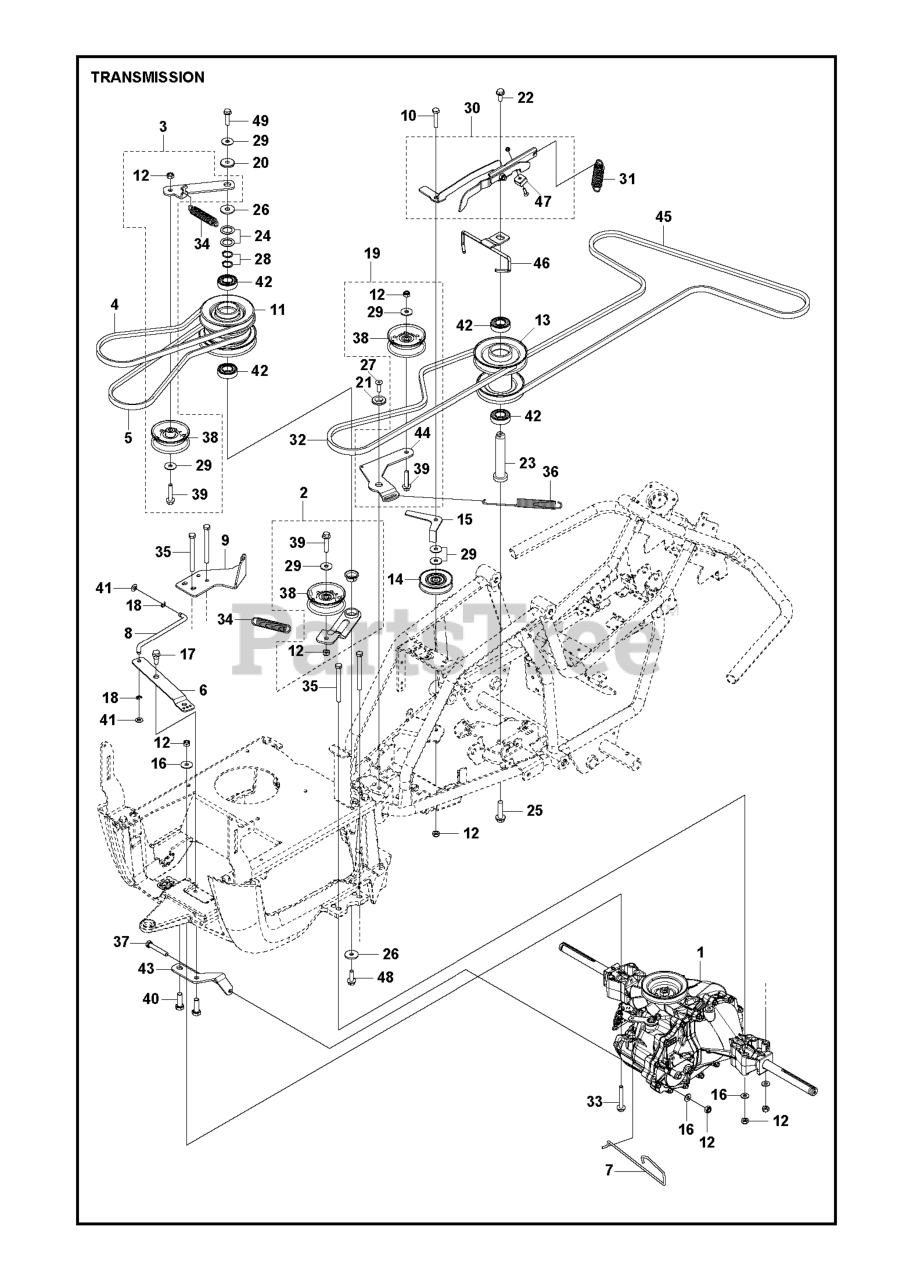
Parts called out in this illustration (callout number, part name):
2	BELT TENSIONER ASSY
3	BELT TENSIONER ASSY
12	LOCKNUT M8
16	WASHER BRB 8.4X17
19	BELT TENSIONER
28	RETAINING RING SGA 20
32	BELT INTERMEDIATE 42 SD
33	SCREW EHHFM
38	IDLER PULLEY
42	BALL BEARING 6004-2RS1
44	BELT TENSIONER
49	BOLT
